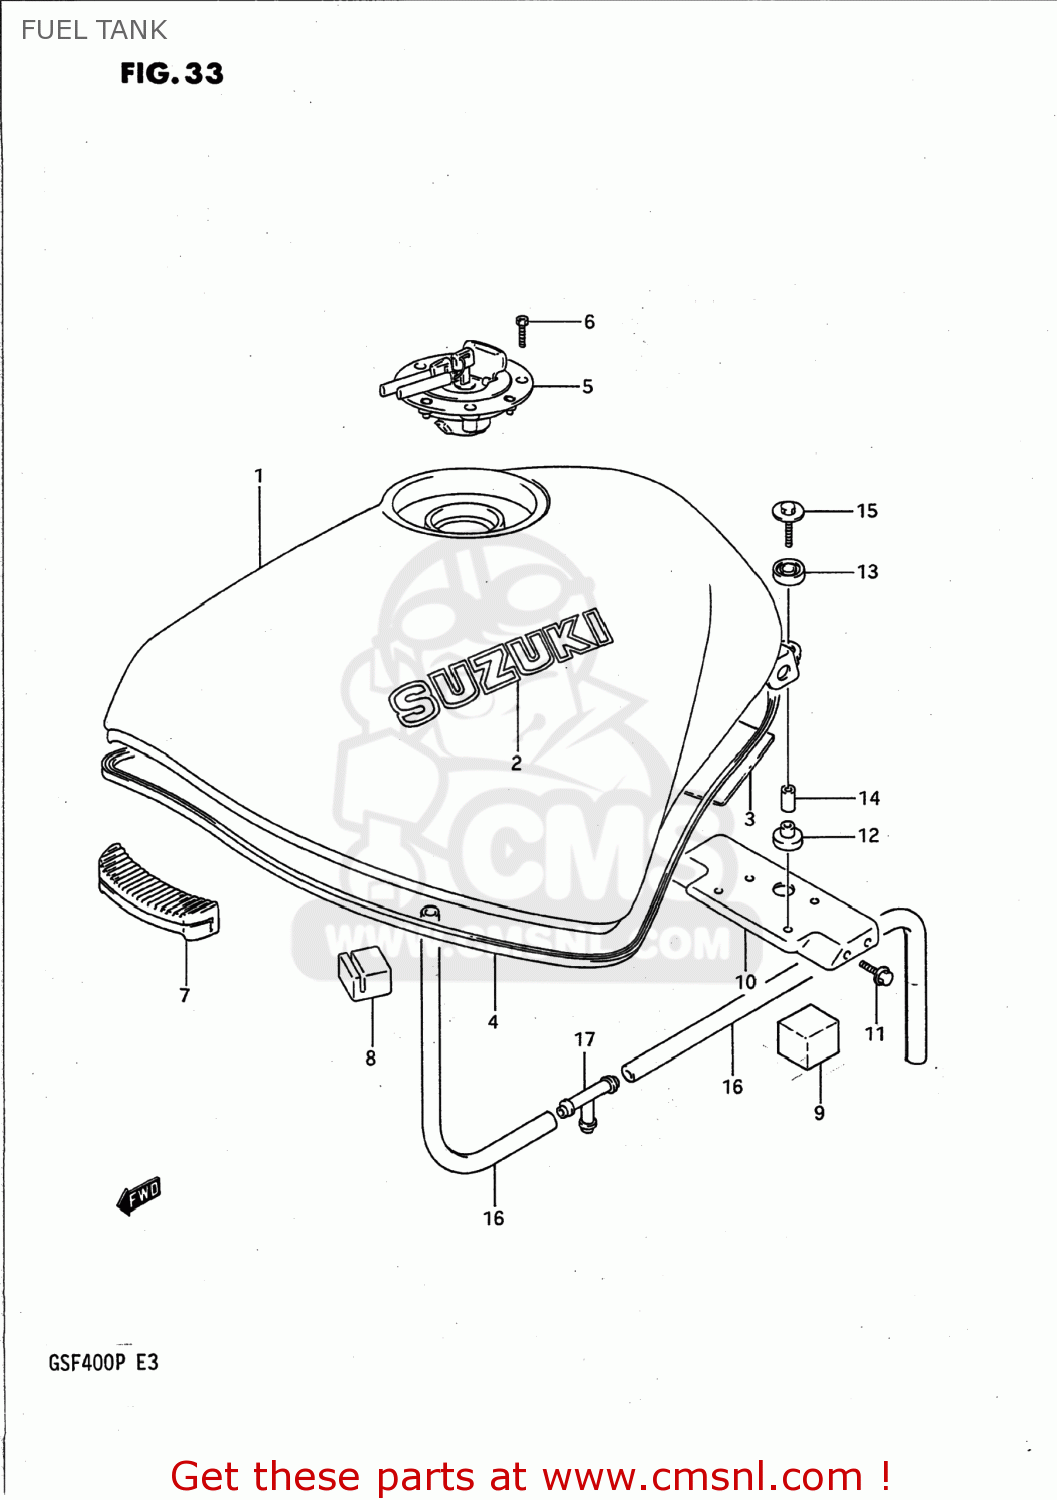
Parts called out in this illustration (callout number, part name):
1	TANK ASSEMBLY,FUEL
2	EMBLEM,FUEL TANK
3	SHEET,FUEL TANK RR
4	MOLDING,FUEL TANK
5	CAP SET,FUEL TANK
6	BOLT(5X20)
7	CUSHION,FUEL TANK FR
8	CUSHION,FUEL TANK SIDE
9	CUSHION,BATTERY 35X35X
10	BRACKET,FUEL TANK RR
11	BOLT 6X12
12	CUSHION
13	CUSHION
14	SPACER
15	BOLT
16	HOSE(7X10.2X600)
17	3 WAY
